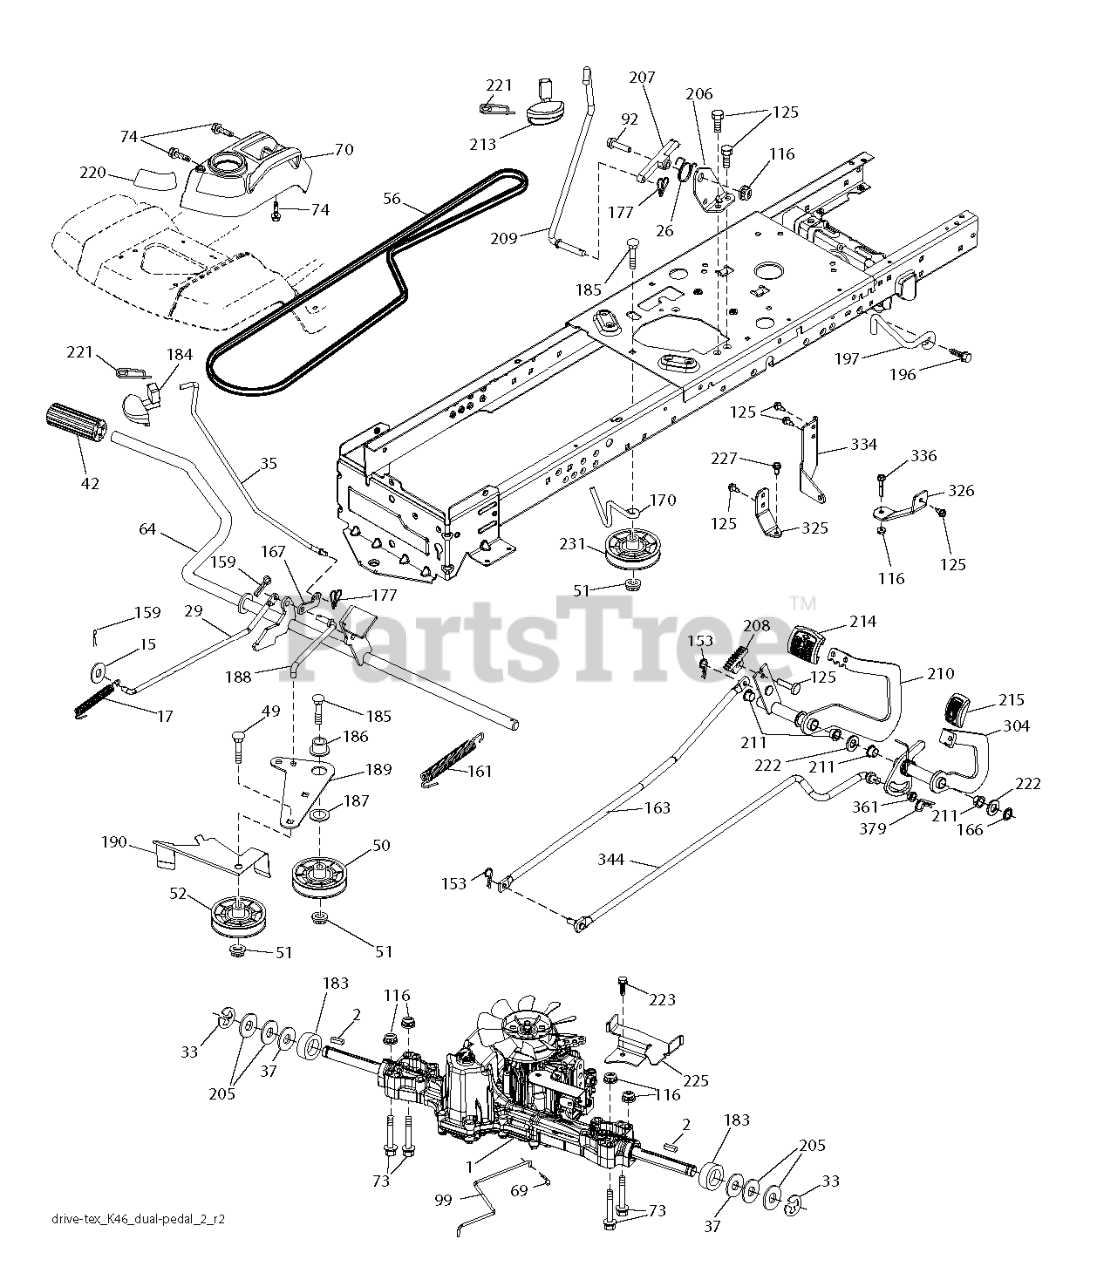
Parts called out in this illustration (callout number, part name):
2	SQUARE KEY
15	WASHER
17	SPRING.BRAKE.K46.GREEN
26	SPRING.RETURN.CRUISE
29	ROD.BRAKE.K46
35	ROD ROD.PARKINGBRAKE.GT.HUSQ/P
37	WASHER.HARDENED
42	PEDAL COVER
50	IDLER.FLAT.910.OFFSET
51	NUT LOCK FLG 3/8-16 UNC
52	IDLER.V-GROOVE.910.OFFSET
64	SHAFT.ASM.PEDAL.BRK.CNTR
69	HAIRPIN.SOFT.ZINC.059X1.125
70	CONSOLE.ASM.RH.GT.FC.HUSQ
99	ARM.PIVOTING.TCRD.GEN2.5.BAGGE
125	SCREW
153	RETAINER M
161	SPRING, RETURN LT
166	NUT.PUSH.625
167	LATCH.BRAKE.SPRING
170	KEEPER.CENTER SPAN.1.688
177	PIN COTTER;LOCKING;BOWTIE;1IN
183	SPACER AXLE
184	HANDLE.PARKING.BRAKE.H (BLK)
186	SPACER.RETAINER
188	LINK.CLUTCH.GROUND DRIVE.LONG
189	BELLCRANK.GROUND.DRIVE.TEX.
190	KEEPER.BELLCRANK.DRIVE
196	SCREW 3/8-16X1
197	BRKT.42.FCS.CLUTCH.ANTIROTATIO
206	BRACKET.MOUNT.CRUISE.LATCH
209	ROD ROD.CRUISECONTROL.GT.HUSQ/
211	BEARING.NYLON
213	KNOB.CONTROL.CRUSIE.HU
214	PEDAL.FORWARD.PAD.TEX
220	REFLECTOR.RH.TEX GT
221	RETAINER.SPRING.CLIP.H
222	WASHER 21/32 X 1-1/4 X 10 GA.
225	KEEPER.BELT.TRANSAXLE.K46
231	IDLER.V-GROOVE.1.688.OFFSET
325	TORQUE.STRAP.K46.LT.LH
326	BRCKT.PNT.TRQ.STP.46.18TIRE.RH
334	SWAY.ROD.BRACKET.K46.X431
